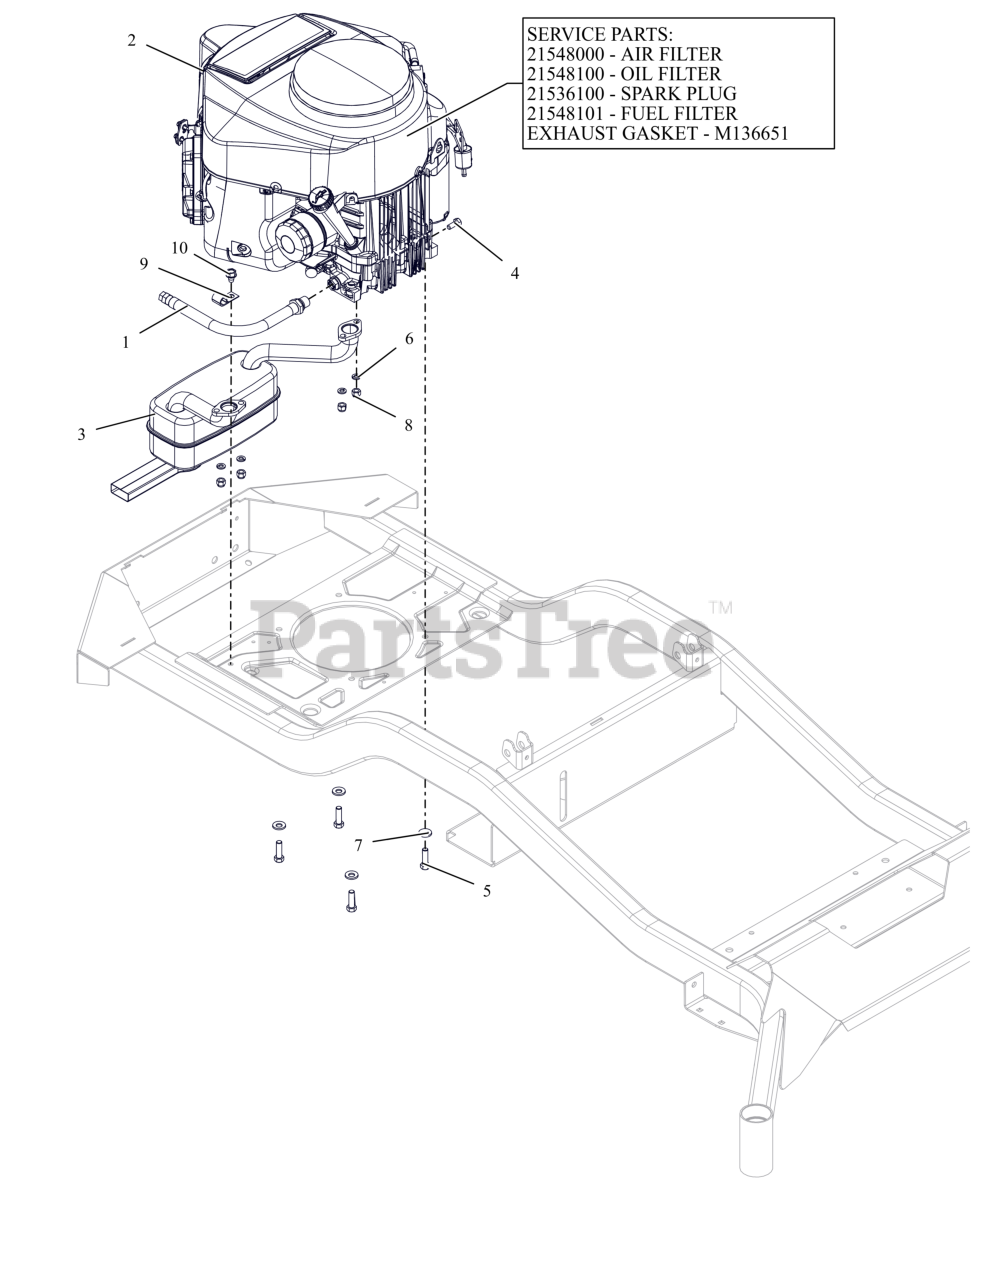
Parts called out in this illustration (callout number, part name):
1	HOSE, OIL DRAIN
1	AIR FILTER, KAWASAKI FR
1	OIL FILTER, KAWASAKI FR
1	PLUG, SPARK
1	FUEL FILTER-KAWASAKI FR
1	GASKET, MUFFLER #
2	ENGINE, KAWASAKI FR730 24HP
3	MUFFLER, KAWASAKI
4	BLT, HEX M8-1.25X20 G8.8 ZCC
5	BLT, HEX .38-16X1.25 G5 ZCC NT
6	WSHR,LK-REG .312X.078 ZCC
7	WASHER, 3/8" SPRING DISC
8	NUT, LK-CTR-JAM M8-1.25 GR8.8 ZC120
9	J-CLAMP
10	SCR,TAP .375-16X.50 HWH TR ZCC
